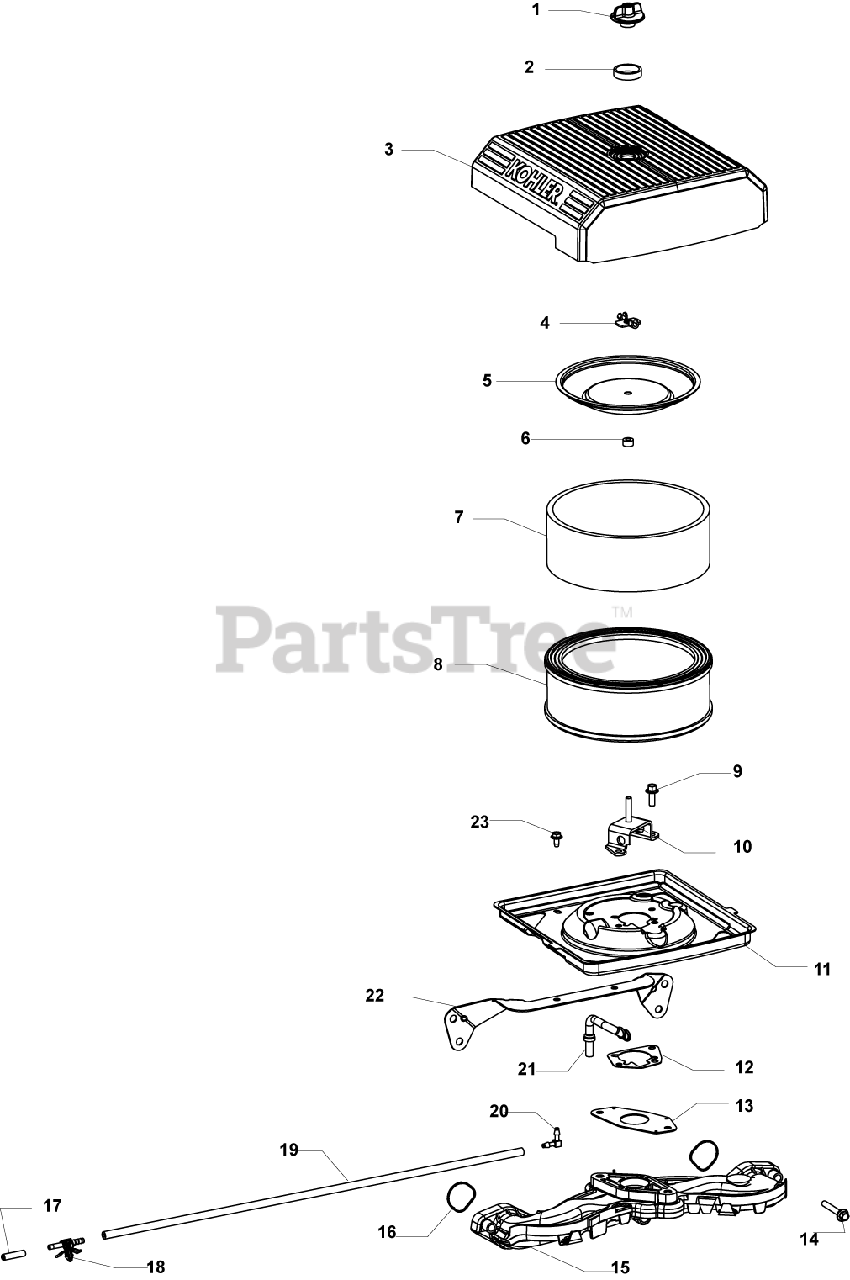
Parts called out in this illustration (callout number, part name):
1	KNOB, COVER
3	COVER, AIR CLEANER
4	NUT, WING
5	COVER, INNER AIR CLEANER
6	SEAL, INNER AIR CLEANER
7	ELEMENT, PRECLEANER (LOW)
8	ELEMENT, AIR CLEANER - Also available Retail Packaged 47 883 03-S1 Air Filter Kit
11	KIT, AIR CLEANER BASE
13	GASKET, CARBURETOR
14	SCREW, FLG M6X1.0X40
15	KIT, INTAKE MANIFOLD USE 24 164 266-S
16	O-RING, INTAKE PORT
20	CONNECTOR, EVAPORATIVE HOSE
21	HOSE, EVAPORATIVE-USE 24 326 131-S
23	SCREW, FLG THD FRM M5X.8X10
